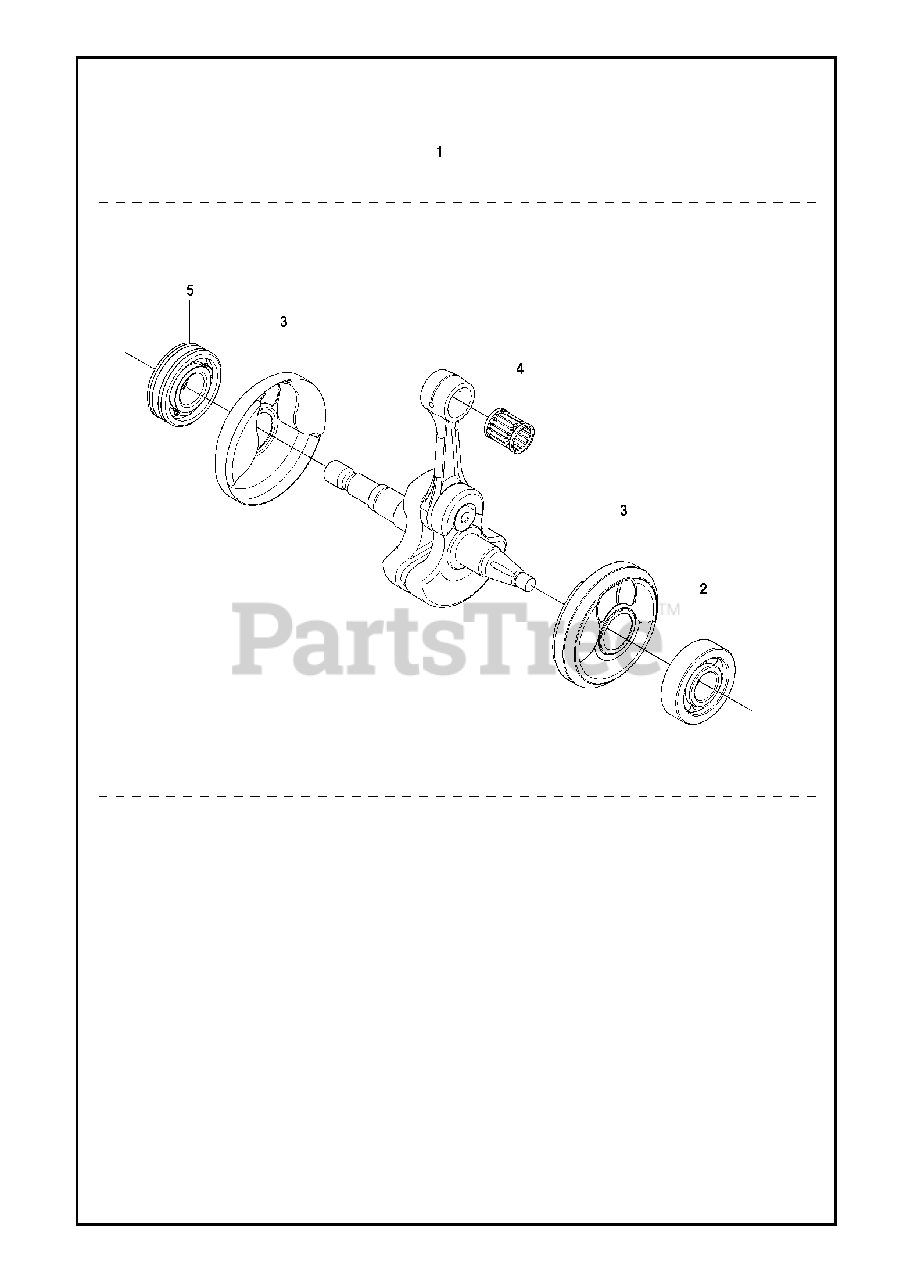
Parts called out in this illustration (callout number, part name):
1	CRANKSHAFT ASSY
2	BALL BEARING
4	NEEDLE BEARING
